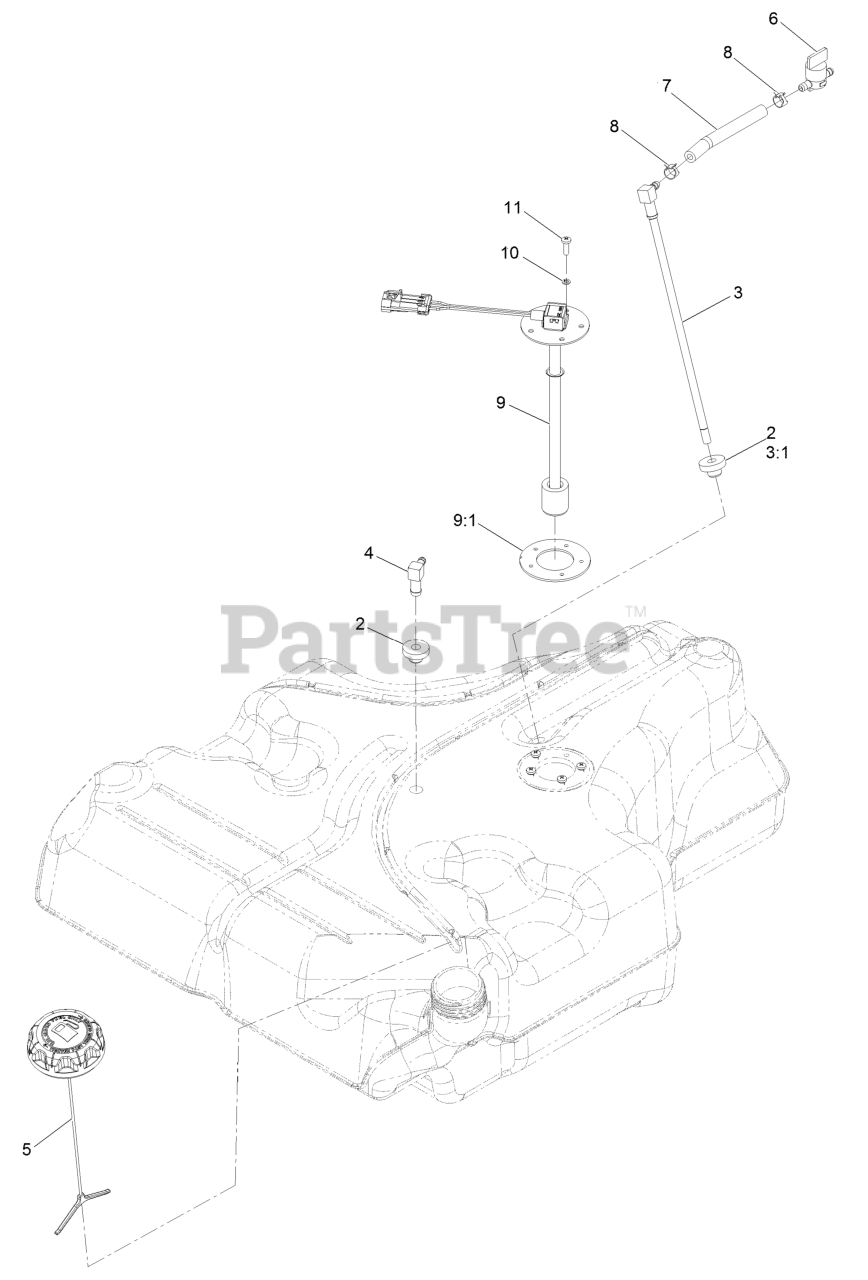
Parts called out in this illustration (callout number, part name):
2	BUSHING
3	FUEL LINE KIT (WITH GROMMET)
3:1	BUSHING
4	FITTING-90 ELBOW
5	CAP-FUEL, RATCHETING
6	VALVE-FUEL
7	HOSE-FUEL
8	CLAMP-HOSE
9	SENDER-LEVEL, FUEL (W/GAS
9:1	Gasket-Sender
10	WASHER-LOCK
11	SCREW-PPH
